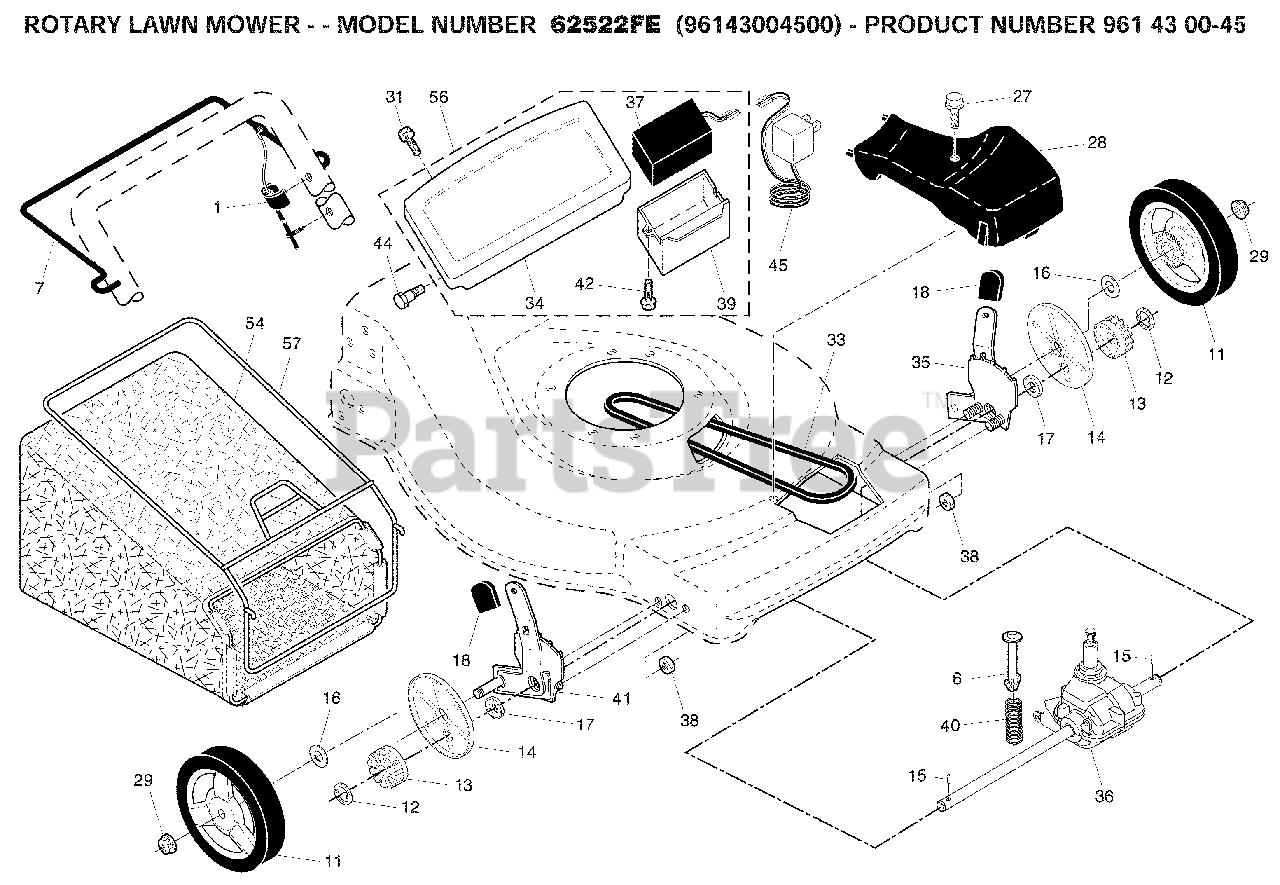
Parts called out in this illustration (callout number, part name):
1	Drive Control Cable
6	Retainer, Spring
7	Bar, Drive Control
11	Wheel & Tire Assembly
13	Gear, Pinion
14	Dust Cover
15	Pawl, Drive
16	Washer, Flat 3/8
17	Ball Bearing
18	Selector Knob
27	Pan Head Tapping Screw #10-24 x 2-3/4
28	Drive Cover
29	Locknut, Hex
31	Screw, Torx Pan Head #20
33	V-Belt
35	Kit, Wheel Adjuster, LH
36	Gear Case Assembly, Complete
37	Battery
38	Locknut, Hex 1/4-20
39	Box, Battery
41	Kit, Wheel Adjuster, RH
42	Screw, Hex Head #13 x 1/2
44	Screw, Shoulder, Hex Head #10-28 x 5/8
45	Charger, Battery
54	Grassbag Assembly
56	Trimplate / Battery / Battery Box Assembly
57	Frame, Grassbag
